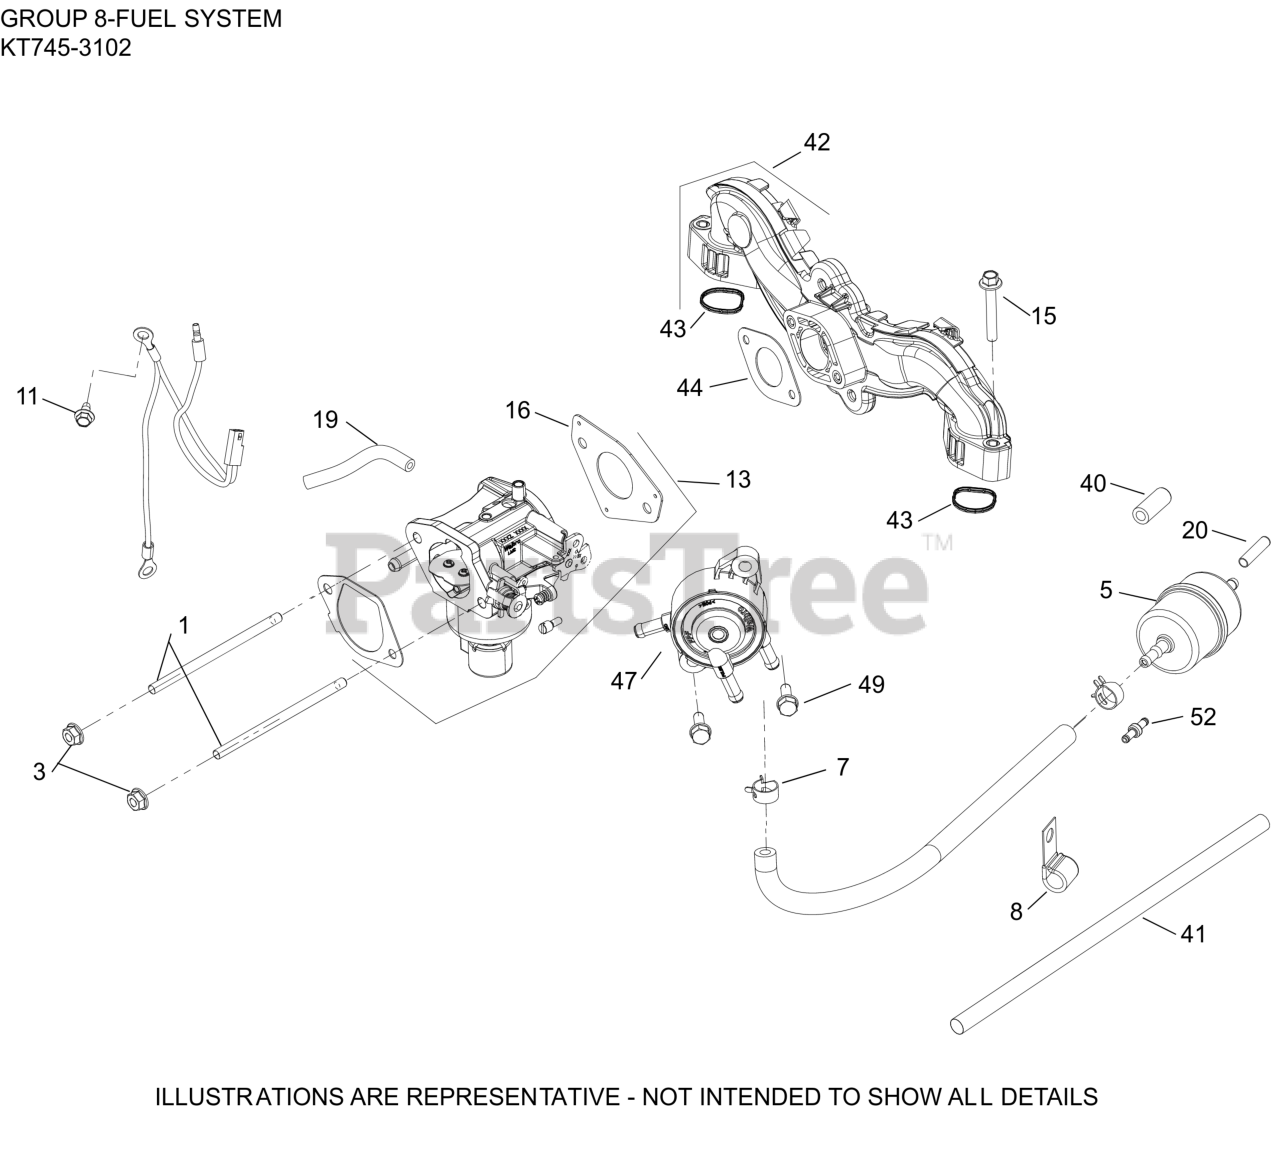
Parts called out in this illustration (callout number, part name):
3	NUT, FLG M6X1.0
5	FILTER, FUEL
7	SPRING CLAMP, HOSE
8	CLIP, CABLE (KM)
11	SCREW, THREAD FORMING
13	KIT,CARB(WALBRO)
15	SCREW, FLG M6X1.0X40
16	GASKET, CARBURETOR-(#2404191S)
19	HOSE, EVAPORATIVE 20"- (#24326143S)
20	CAP, MASKING
40	MASKING CAP
41	SLEEVE, ANTI-ABRASION
42	INTAKE MANIFOLD W/GASKETS
43	O-RING, INTAKE PORT
44	GASKET, CARBURETOR (PIM, CV)
47	PUMP, FUEL (PULSE)
49	SCREW, HEX HEAD
52	FITTING, FUEL SYSTEM
NI	KIT,REPAIR OVERHAUL(WALBRO)
NI	KIT,BOWL O-RING(WALBRO)
NI	KIT, HIGH ALT (4000-8000 FT)(WALBRO)
NI	KIT,SOLENOID REPAIR(WALBRO)
NI	KIT,REPAIR FLOAT(WALBRO)
